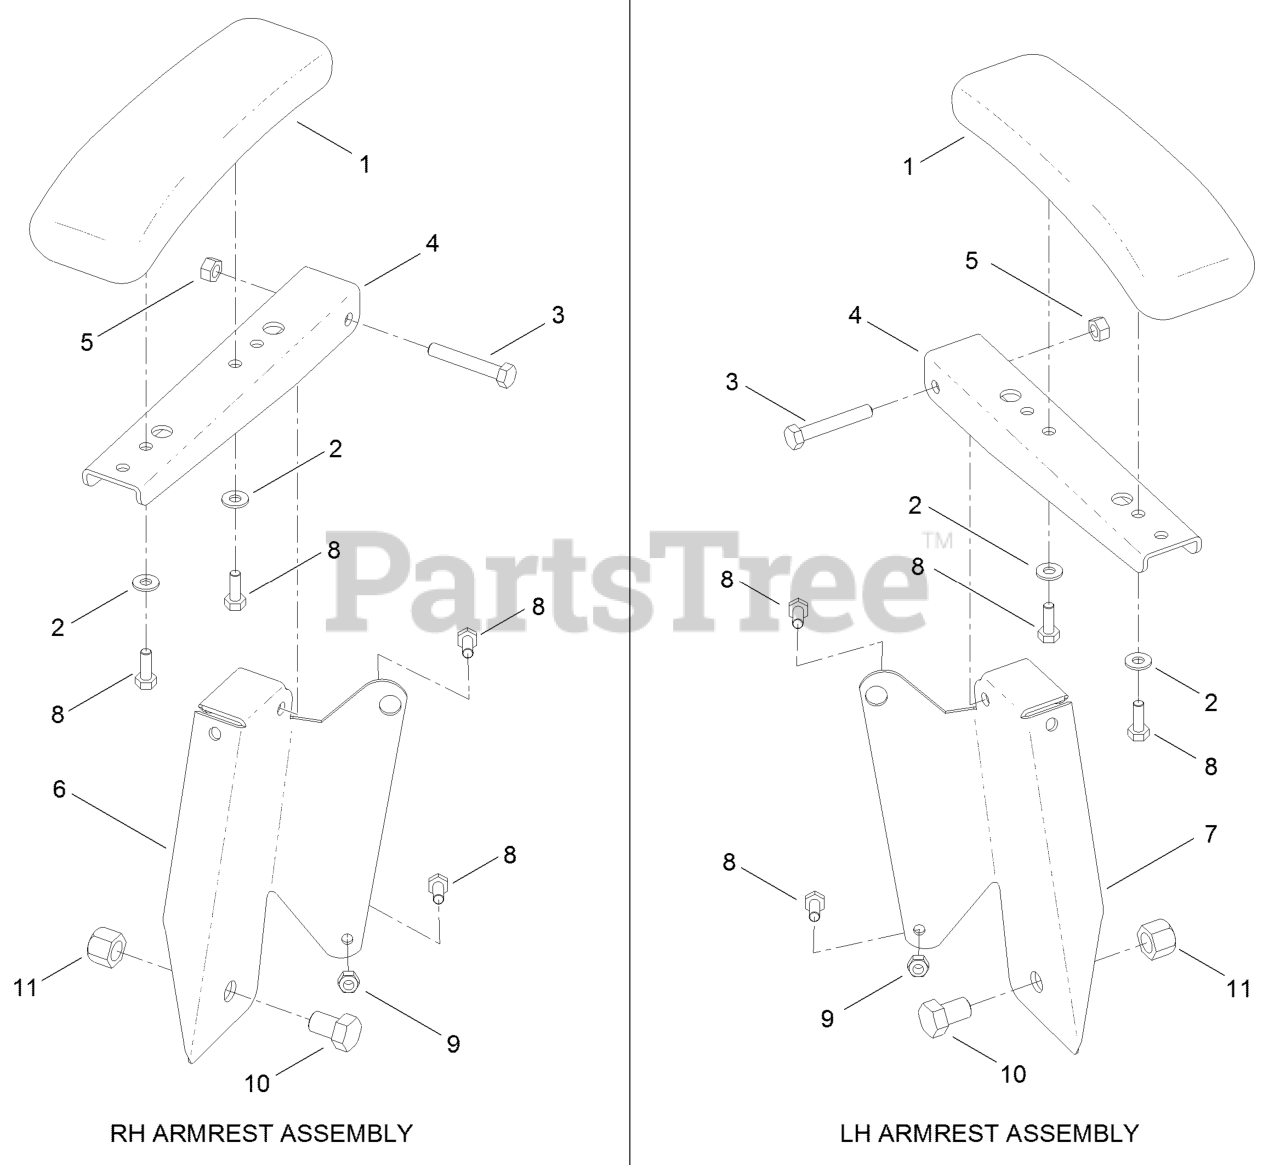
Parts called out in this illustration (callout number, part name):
1	CUSHION-REST, ARM
2	WASHER-FLAT
3	SCREW-HH
4	CHANNEL-ARMREST
5	NUT-HEX, SIDE DEFORM
6	BRACKET-ARMREST, RH
7	BRACKET-ARMREST, LH
8	SCREW-HH
9	NUT-LOCK, NI
10	SCREW-HH
11	NUT-LOCK, NI
